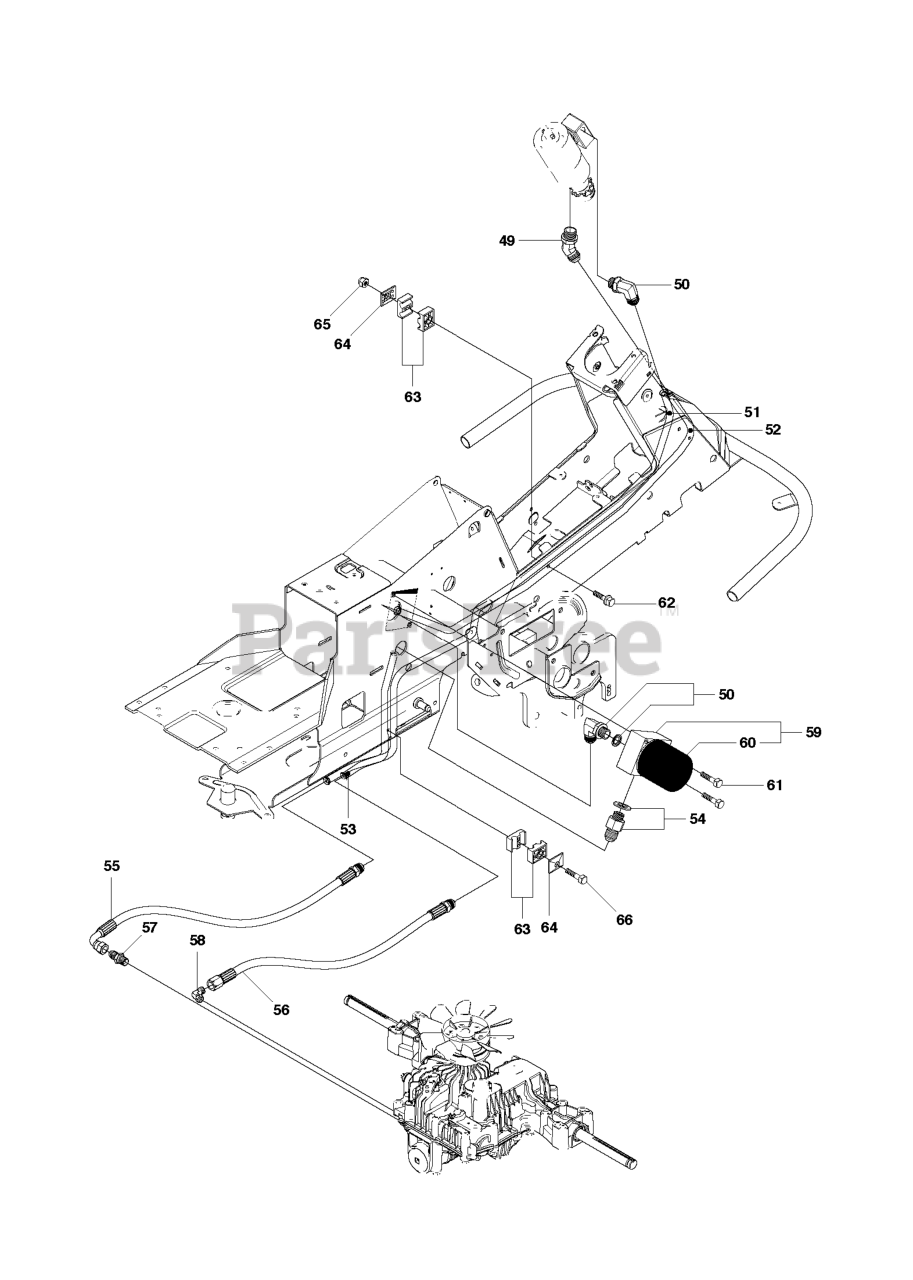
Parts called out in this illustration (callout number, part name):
60	FILTER
63	PIPE CLAMP
65	LOCKNUT M6
